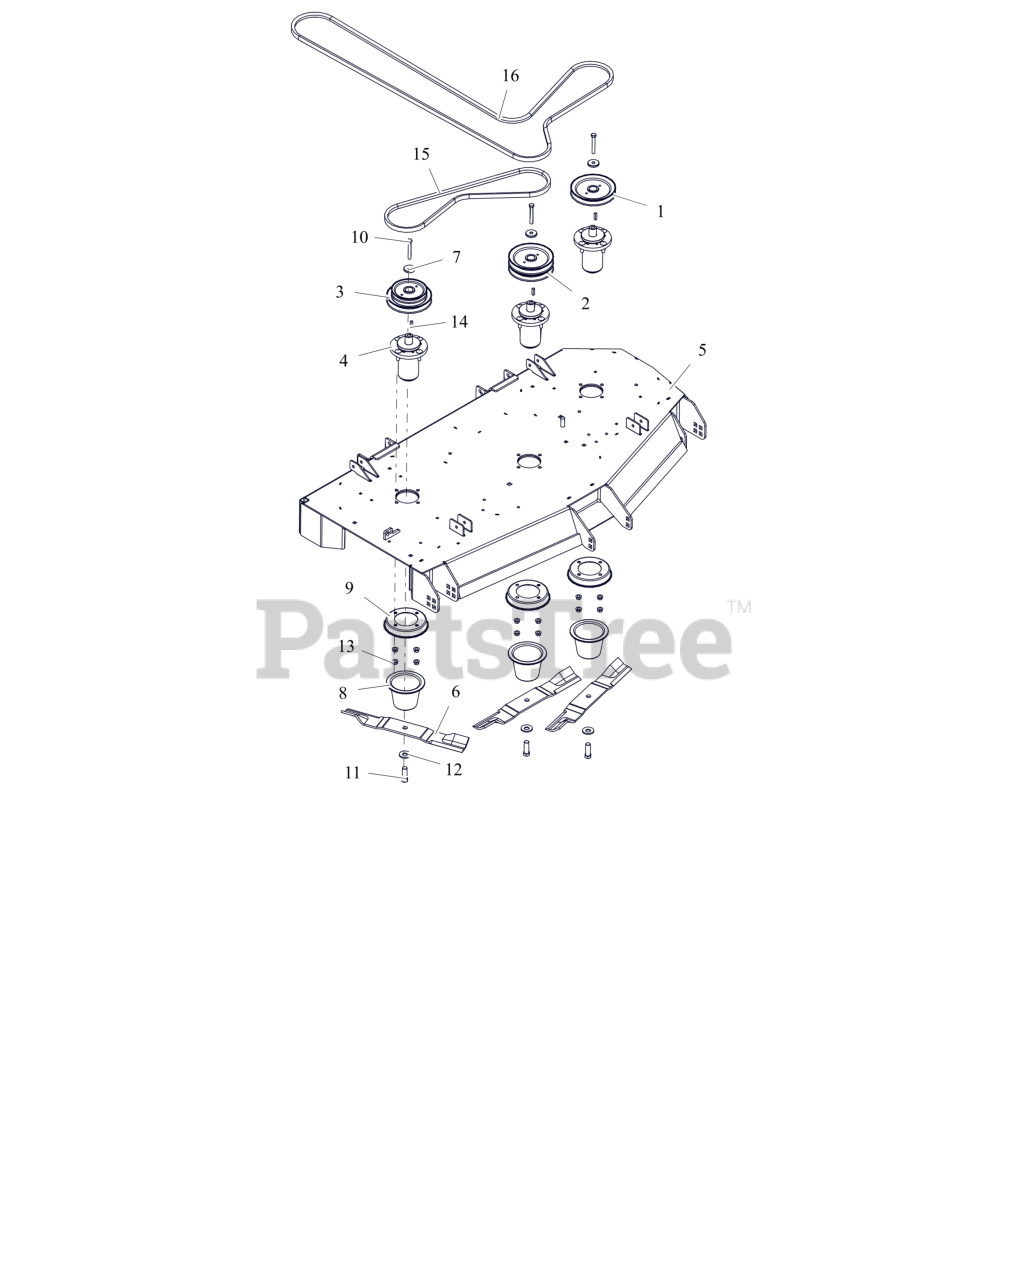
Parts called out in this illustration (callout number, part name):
1	PULLEY, SINGLE -1.000 ID X 6.000 OD
2	PULLEY, DOUBLE 1.000 ID X 6.000 OD
3	PULLEY, DBL-1"IDX6.00"&4.75"OD
4	ASM, MAINT FREE ALUM SPINDLE
5	WLDMT, 52" SIDE DISCH DECK X3 (RED) W/ SAFETY DECALS
6	BLADE, 18.00" MOWER (HI-LIFT)
7	RETAINER, SHEAVE
8	GUARD, SPINDLE LOWER
9	GUARD, SPINDLE TOP
10	BLT, HEX .38-16X2.75 G8 ZCC
11	BLT, HEX .62-18X1.75 G8 ZCC
12	WSHR-BLVL .669X1.535X.138
13	NUT-LK-CTR-FLG .375-16 GF ZCC
14	KEY, SQ .25X.25X1.00 RC 40-50
15	V-BELT, B-COGGED
16	V-BELT, B SECTION
